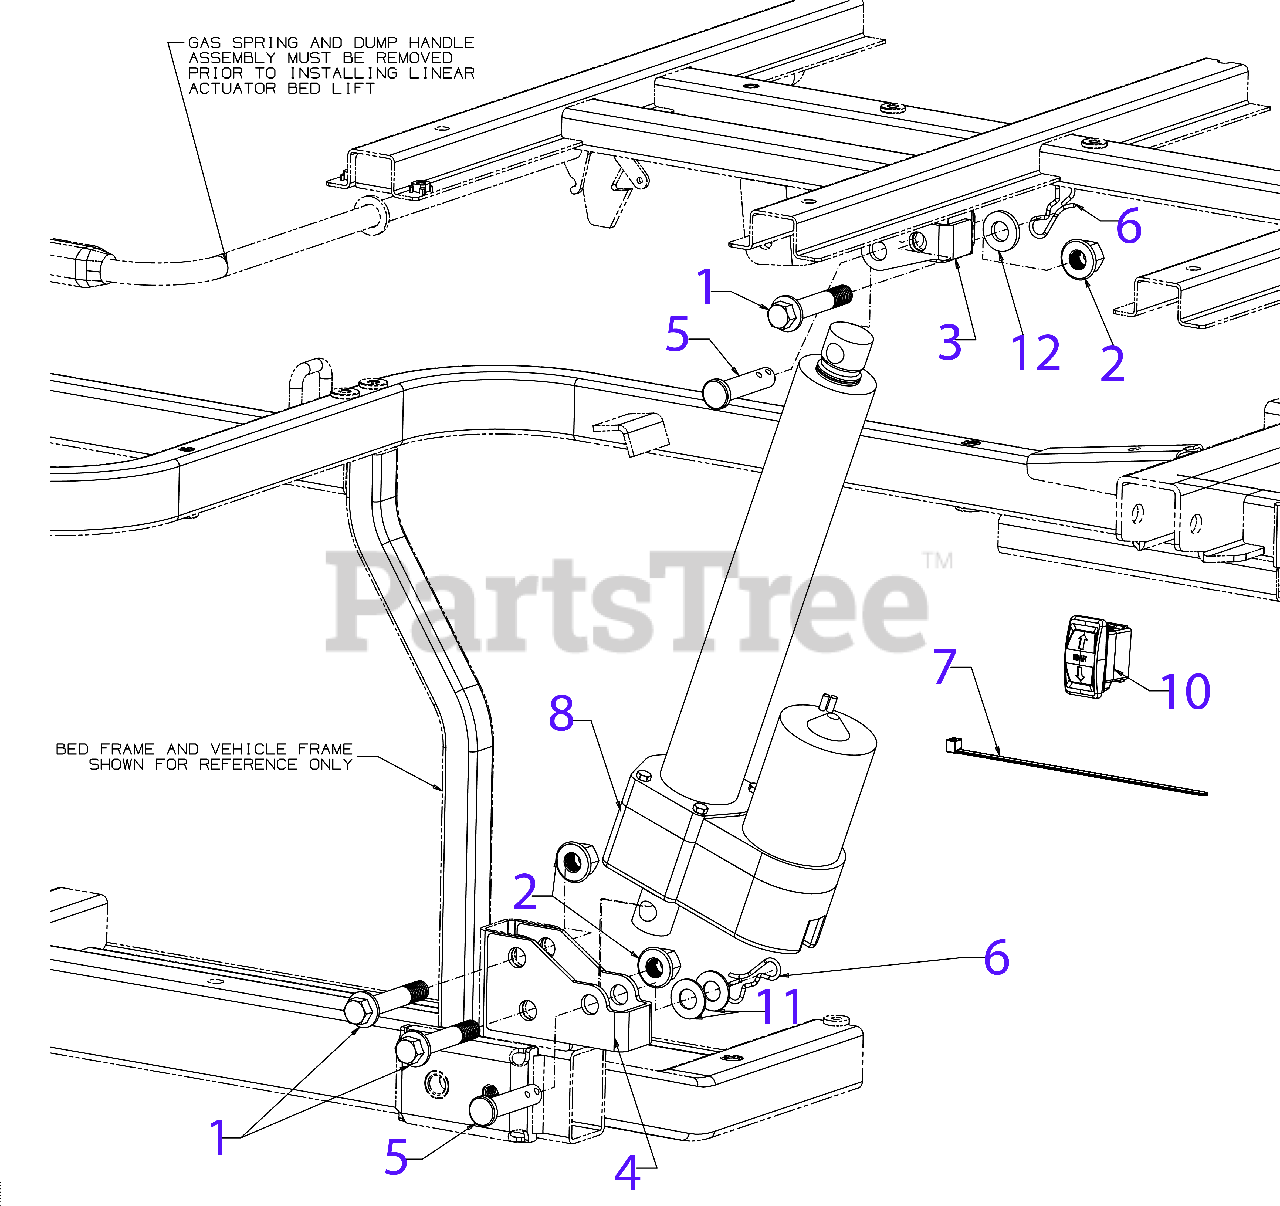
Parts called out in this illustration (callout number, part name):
1	HEX HEAD BOLT M12X1.25-65
2	LOCK NUT M12X1.25
5	CLEVIS PIN .50 x 2.0
6	BOW TIE COTTER PIN
7	7" CABLE TIE
8	ELECTRIC ACTUATOR
10	ROCKER SWITCH
11	FLAT WASHER .510X.995
12	FLAT WASHER
